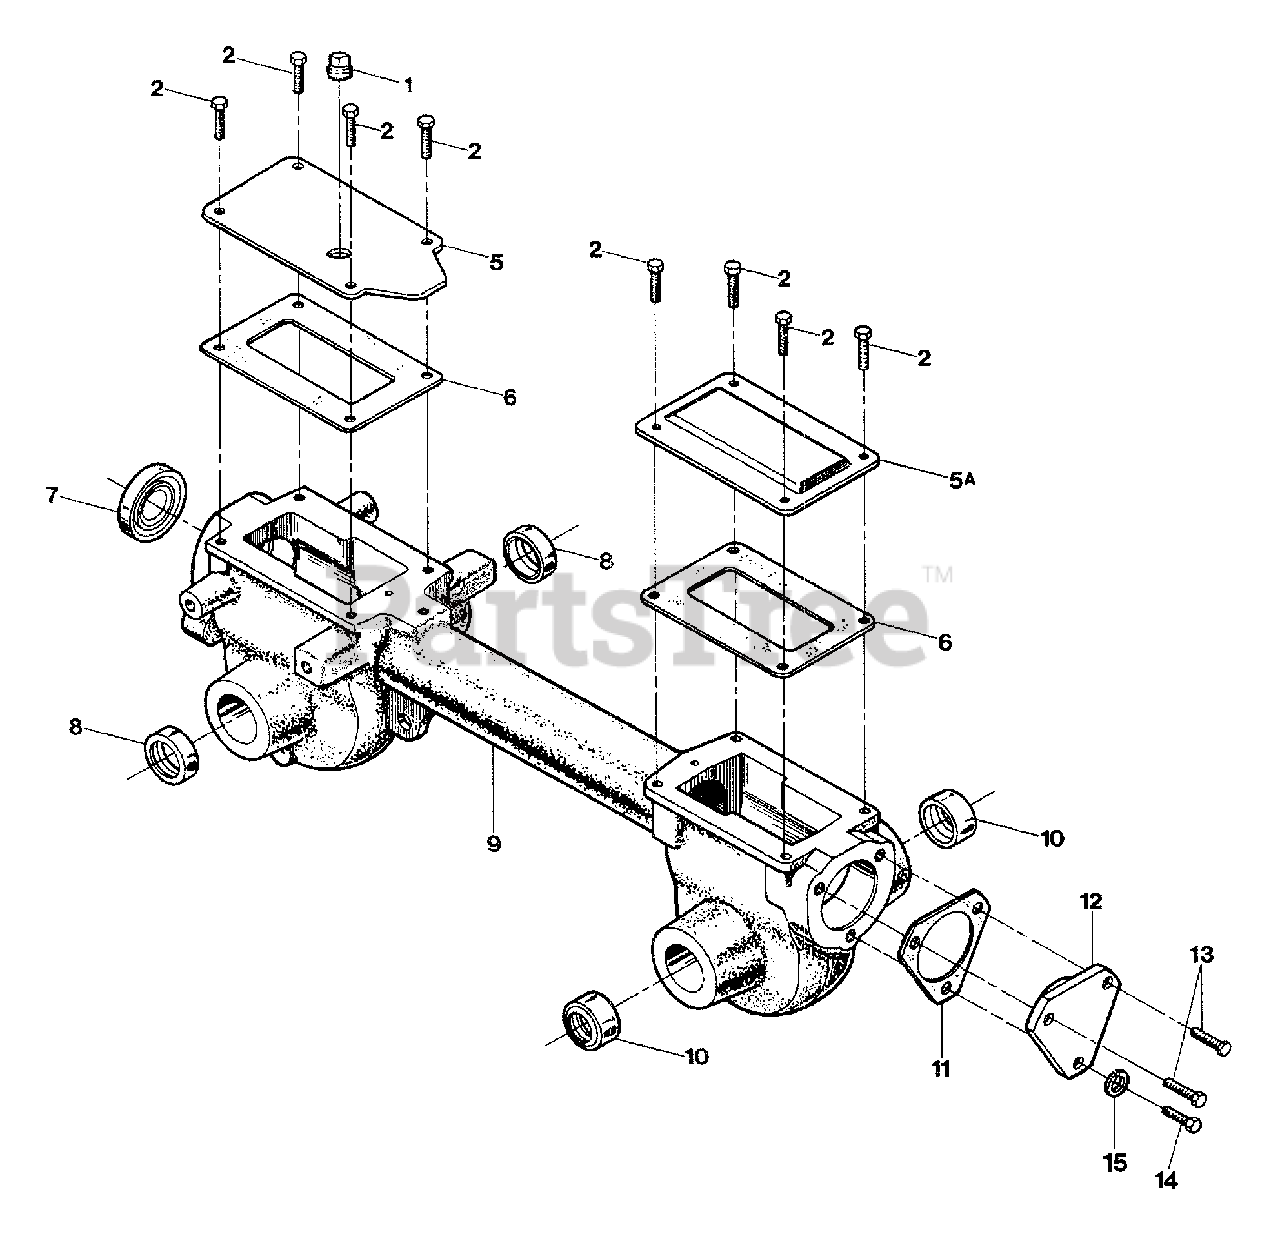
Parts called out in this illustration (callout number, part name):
1	Plug, Transmission Oil Fill
2	Hex Hd. Flange Screw, 5/16-18 x 5/8, Grade 5
5	Front Cover, Transmission
5A	Rear Cover, Transmission
6	Gasket, Housing Cover
7	Oil Seal, Drive Shaft
8	Oil Seal, Wheel Shaft
9	Transmission Housing Assy
10	Oil Seal, Tine Shaft
11	Bearing Cap Gasket, .010" thick
12	Rear Bearing Cap
13	Hex Hd. Flange Screw, 5/16-18 x 1
14	Hex Hd. Flange Screw, 5/16-18 x 3/4
15	Lock Washer, 5/16
